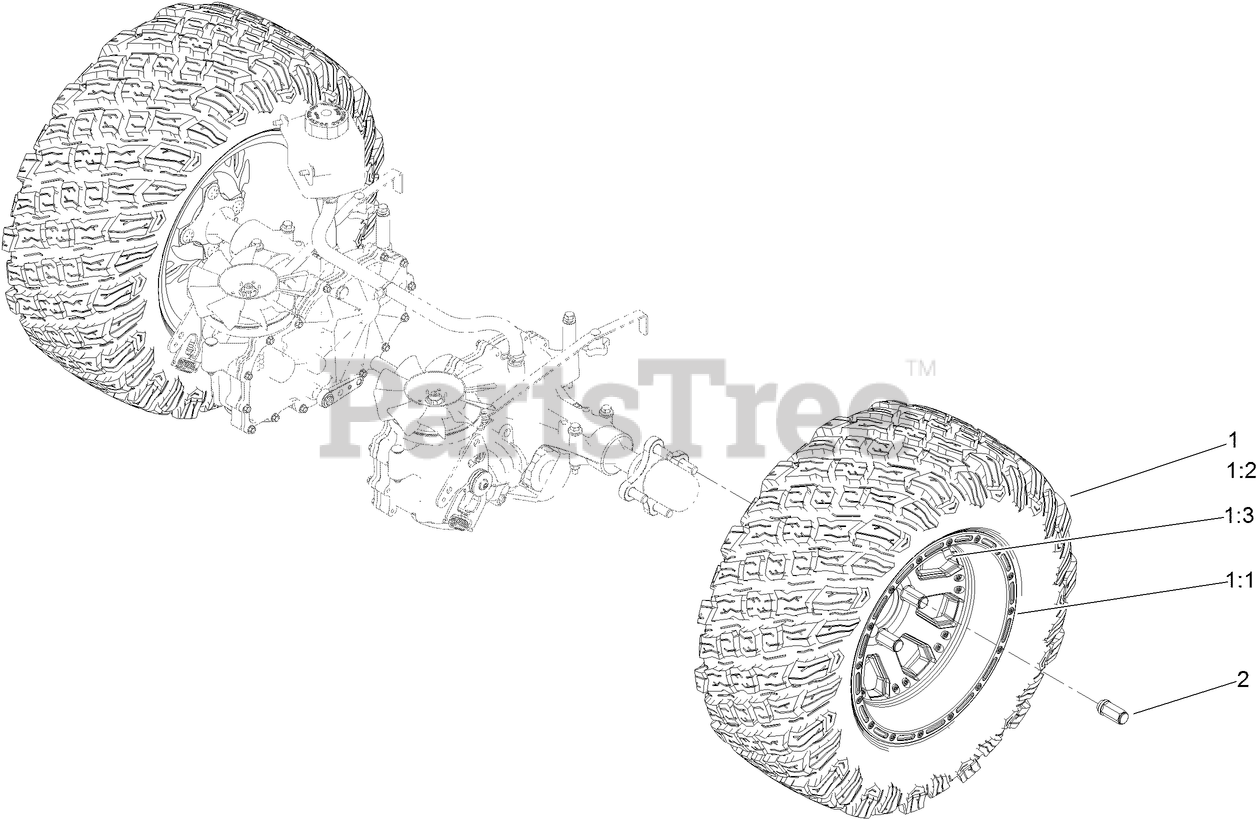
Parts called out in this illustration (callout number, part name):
1	WHEEL AND TIRE ASM
1:1	RIM-WHEEL 12X7
1:2	TIRE-K3012
2	NUT-LUG
